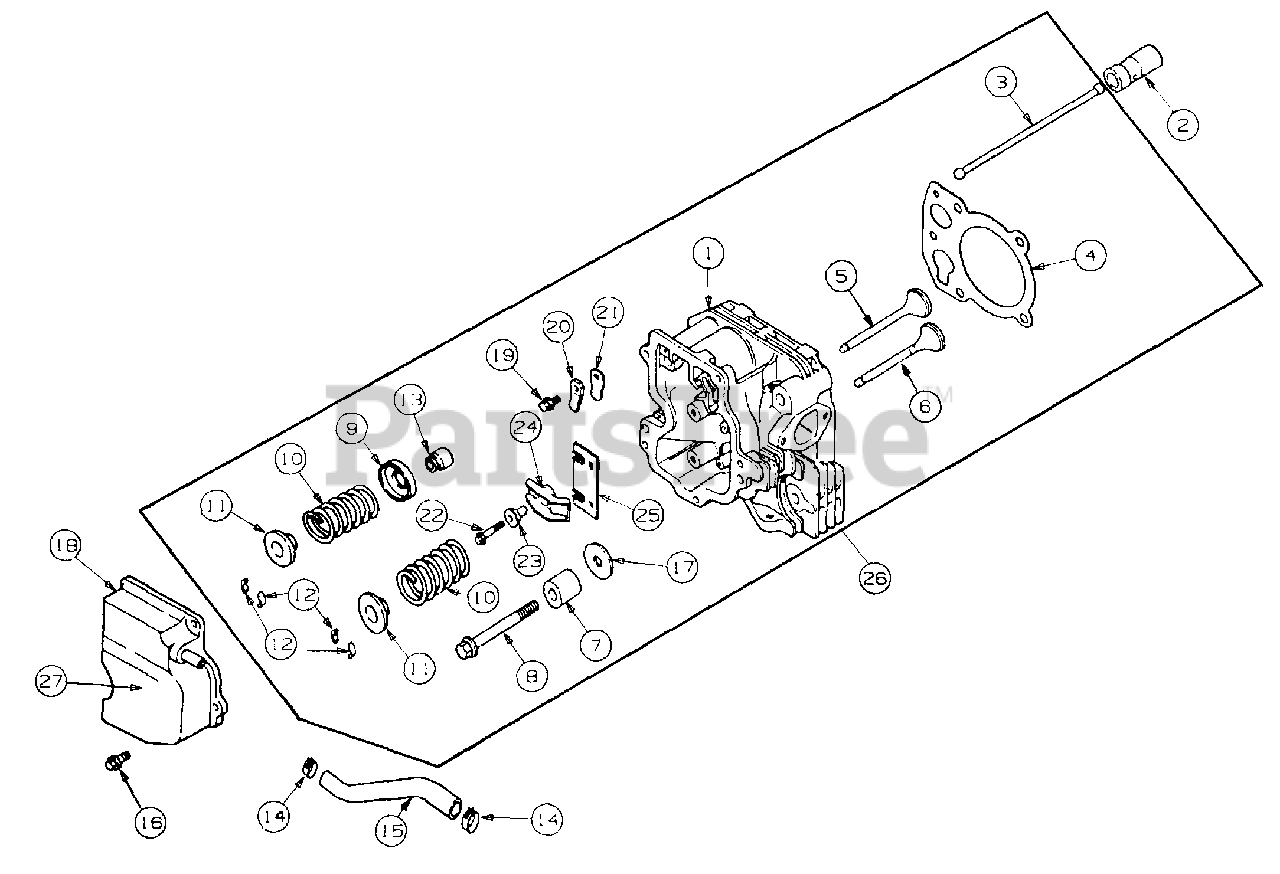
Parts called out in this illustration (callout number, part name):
1	Cylinder Head
2	Lift, Valve
3	Rod, Push
4	Gasket, Cylinder Head
5	Valve, Intake (Std)
6	Valve, Exhaust (Std)
7	Spacer, Head Bolt Exhaust Port
8	Screw, Cyl Head, M10 X 1.5 X 81
9	Retainer, Spring
10	Spring, Intake Valve
11	Cap, Valve Spring
12	Kit, Retainer
13	Seal, Valve Stem
14	Clamp, Hose
15	Hose, Breather
16	Screw, Valve Cover, M6 X 1.0 X 20
18	Cover, Valve w/Nipple
19	Screw, Breather Reed Ret, M5 X 0.8 X 10
20	Retainer, Breather Reed
21	Reed, Breather
22	Screw, Rocker Arm, M6 X 1.0 X 34
23	Pivot, Rocker Arm
25	Plate, Guide
26	Kit, Cylinder Head
27	Graphic, OHV Engine
